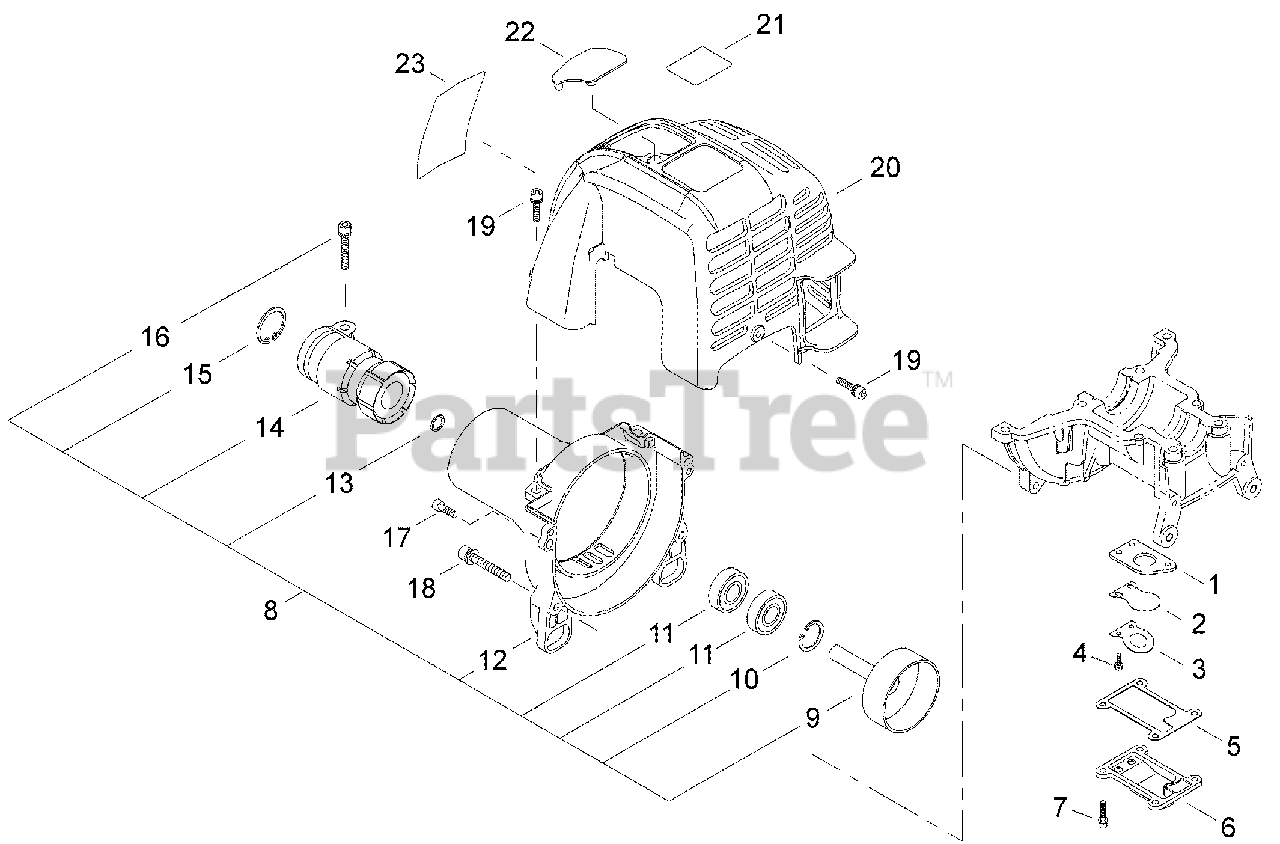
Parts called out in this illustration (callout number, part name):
1	PLATE, REED BACKING
2	VALVE, REED
3	STOP, REED VALVE
4	SCREW - 3X10
5	GASKET, REED VALVE
6	COVER, REED VALVE
7	SCREW - 4X14
8	FAN CASE ASSY
9	DRUM, CLUTCH
10	RING, RETAINING - 28
11	BEARING, BALL - 6001DDUC3
12	CASE, FAN
13	RING, RETAINING
14	CLAMP, MAIN PIPE
15	RING, RETAINING - 42
16	SCREW - 5X22
17	SCREW - 5X16
18	SCREW - 5X40
19	SCREW - 4X14
20	COVER, ENGINE
21	LABEL - MODEL S4000
22	COVER, SPARK PLUG
23	LABEL - E4
